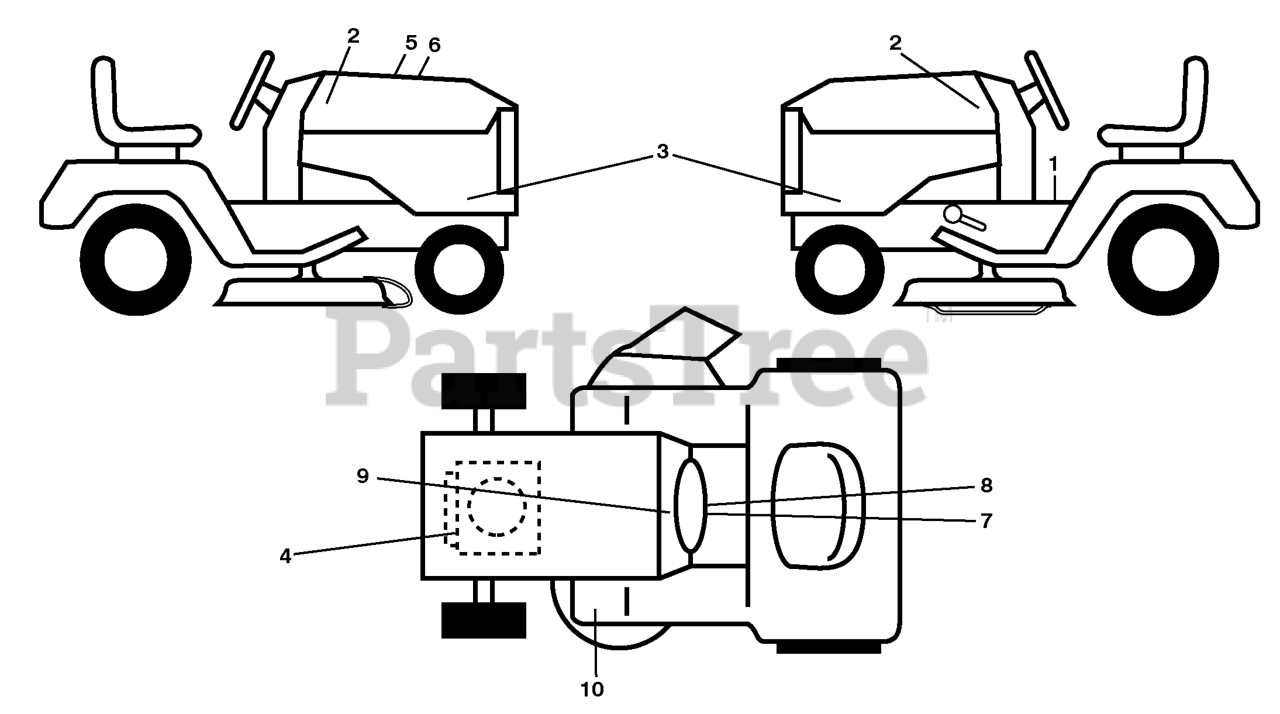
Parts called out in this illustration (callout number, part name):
1	DECAL.FENDER.WARNING.ENG
2	RP.DECAL.BADGE.170MM.TEXTLOGO
3	DECAL.SIDE PANEL YTH22V42LS
4	DECAL, ENG. HP
5	DECAL.WARNING.CUST.RESP.E85.
6	DECAL, REPLACEMENT
7	LABEL EMISS. CA.
8	DECAL, WARNING SPARK ARRESTOR
9	DECAL BTRY SYMBOLS
10	DECAL.PEDAL.HUSQ.CROWN
